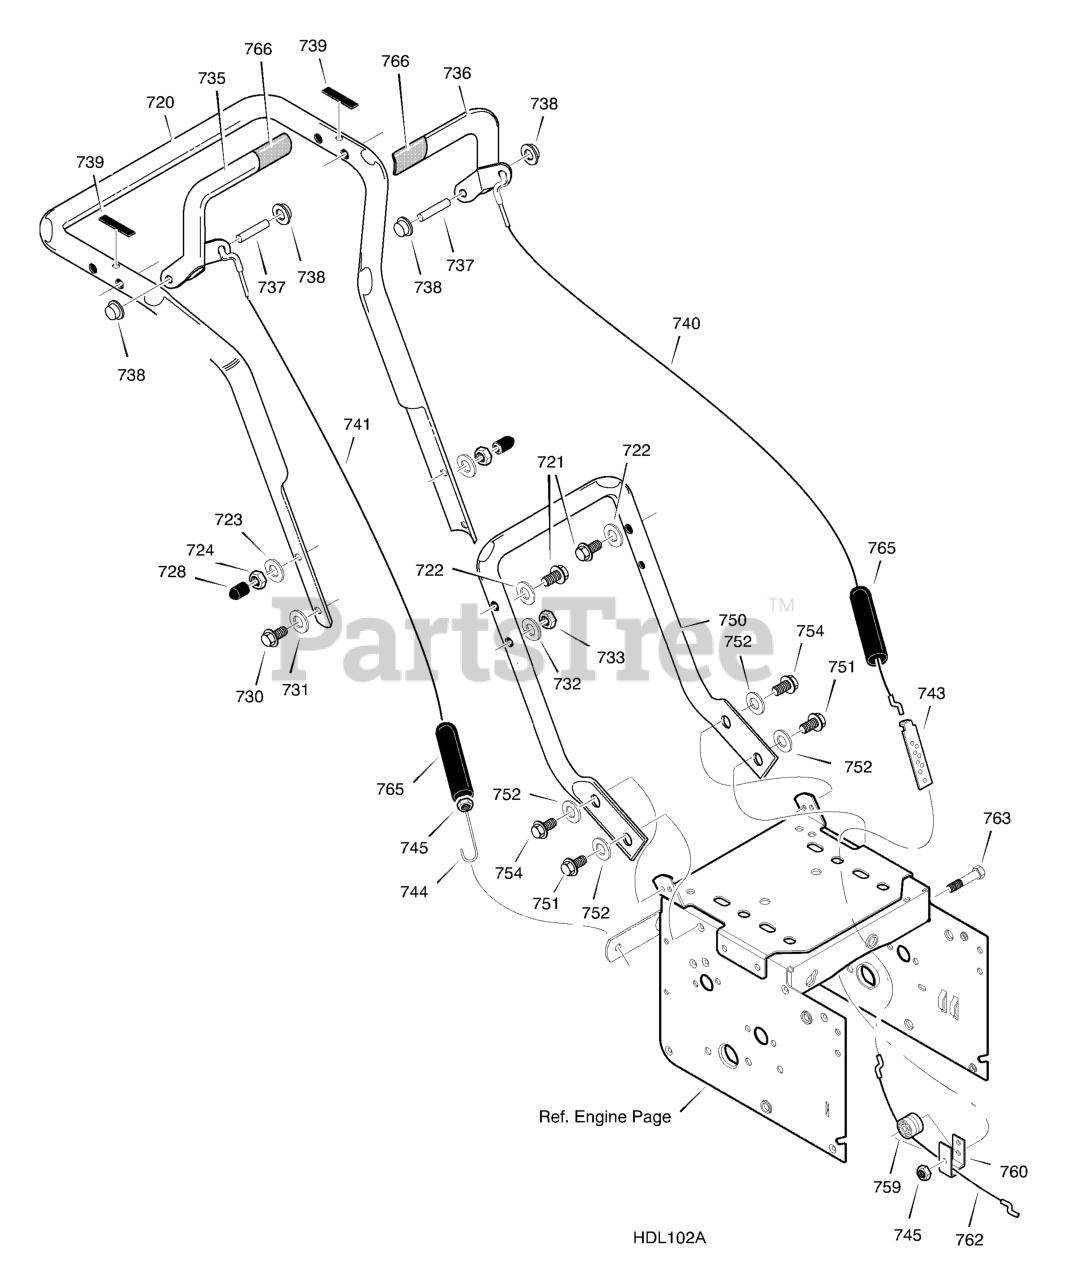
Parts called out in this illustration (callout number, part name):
720	HANDLE, UPPER
721	SCREW, 3/8-16 x 3.00
722	WASHER, FLAT
723	WASHER
724	NUT, 3/8-16
728	STOP, PLASTIC
730	SCREW, 3/8-16 X 2
731	WASHER, FLAT
732	WASHER
733	NUT, 3/8-16
735	HANDLE, RIGHT
736	HANDLE, LEFT
737	PIN, PIVOT CLUTCH
738	NUT, PUSH ON CAP
739	BUMPER, RECTANGLE
740	CABLE, DRIVE
741	CABLE, AUGER CLUTCH
743	BRACKET, CABLE ADJUSTER
744	SPRING, AUGER CLUTCH
745	NUT, 1/4-20
750	HANDLE, LOWER
751	SCREW, TAP 5/16-18 X .75
752	WASHER, SPTLK
754	SCREW, TAP 5/16-18 X .75
759	SPOOL-CABLE, AUGRT CLUTCH
760	BRACKET, CABLE SPOOL YZ
762	CABLE, LOWER DRIVE 12"
763	BOLT, HEX 1/4-20 X 1.75 YZ
765	BOOT, CLUTCH SPRING
